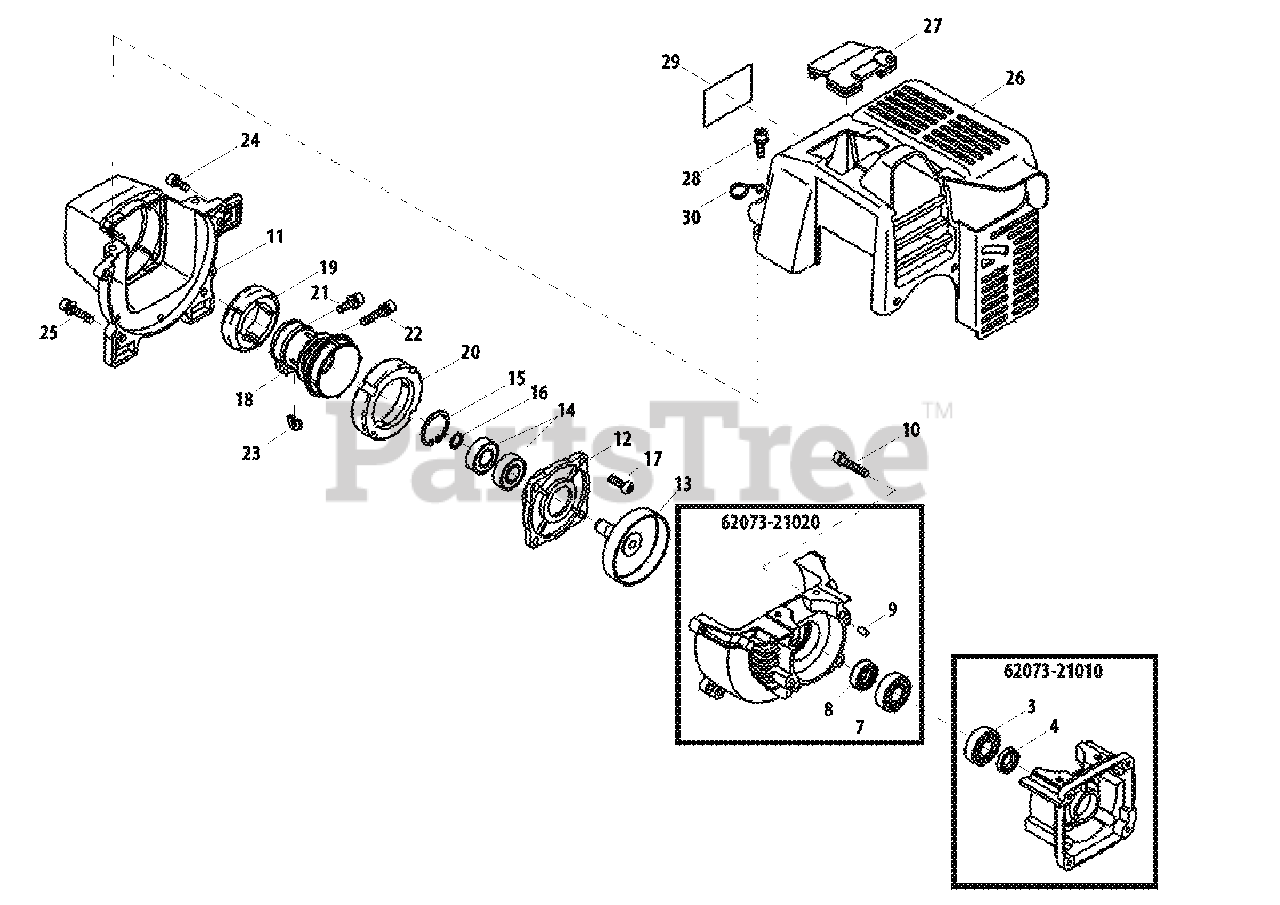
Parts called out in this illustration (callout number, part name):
3	BEARING, BALL - 6201C3
4	SEAL, OIL - 12
7	BEARING, BALL - 6201C3
8	SEAL, OIL - 12
9	PIN - LOCATING
10	SCREW - 5X25
11	CASE, FAN
12	CASE, CLUTCH
13	DRUM, CLUTCH
14	BEARING, BALL - 6001DDUC3
15	RING, RETAINING - 28
16	RING, RETAINING
17	SCREW - 5X20
18	JOINT
19	CUSHION - FRONT
20	CUSHION - REAR
21	SCREW - 5X16
22	SCREW - 6X28
23	SHIM
24	SCREW - 5X18
25	SCREW - 5X30
26	COVER, ENGINE
27	COVER
28	SCREW - 5X16
29	LABEL - TRADE
30	GUIDE, CABLE
6207321010	CRANKCASE ASSY - REAR
6207321020	CRANKCASE ASSY - FRONT
